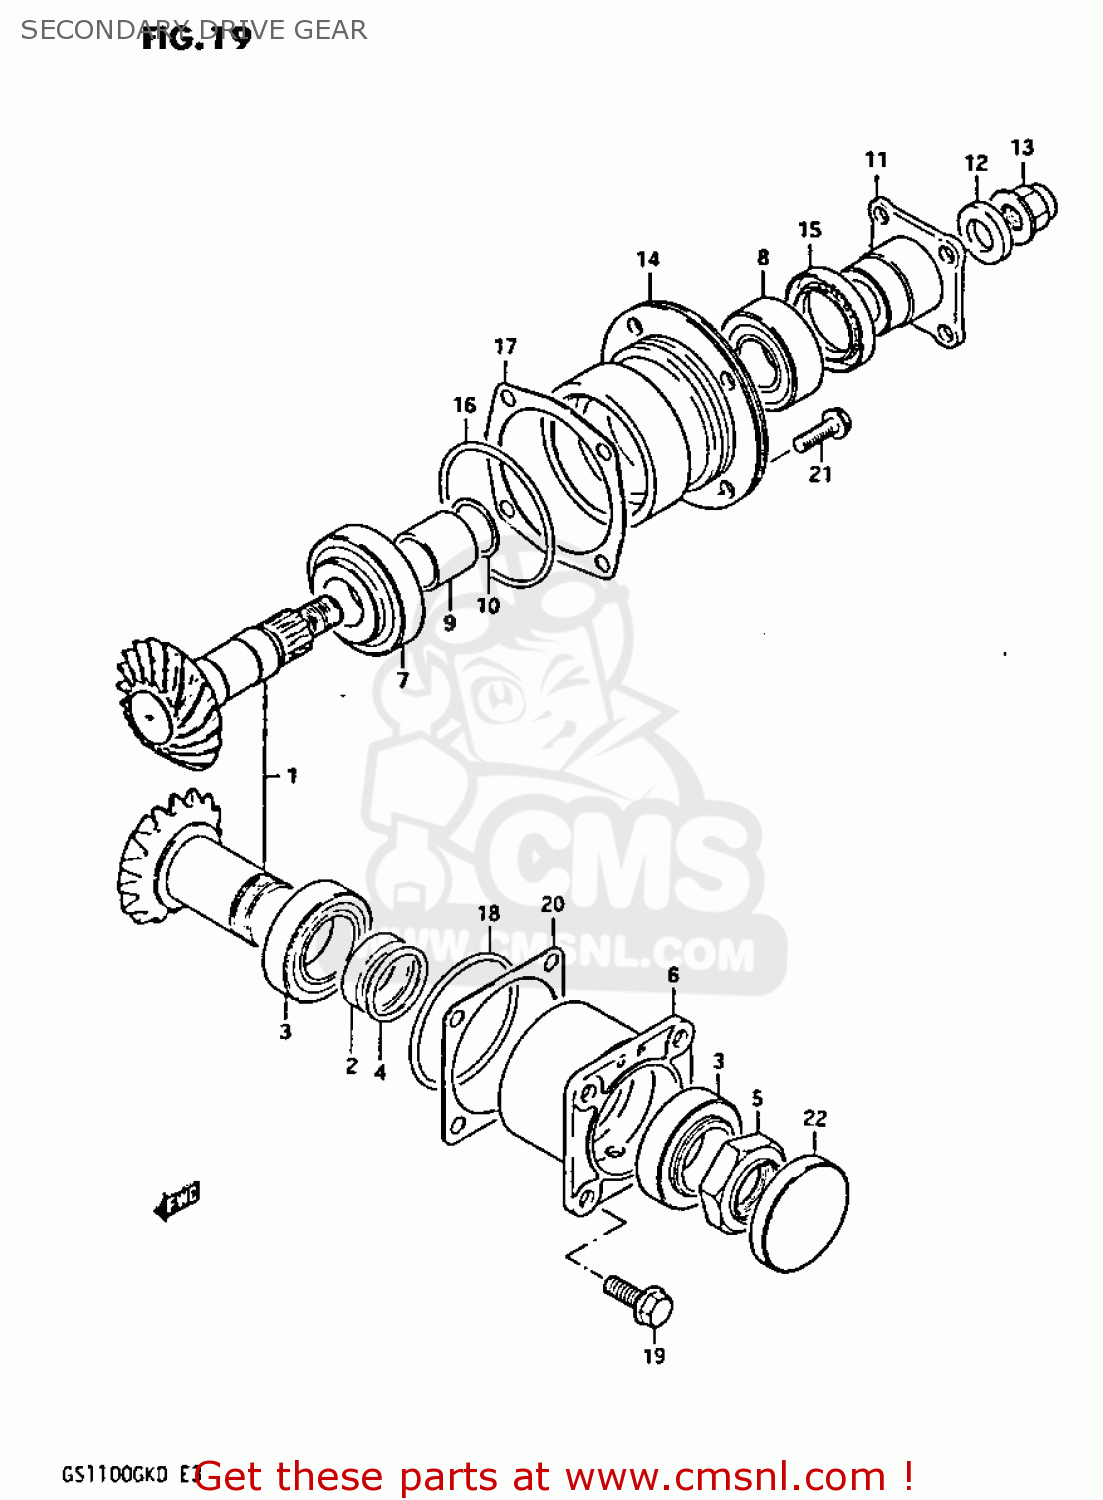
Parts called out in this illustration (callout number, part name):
1	GEAR,SECONDARY DRIVE BEVEL
2	SPACER (32.4X38X12.5)
3	BEARING(32X58X17)
4	SHIM(32X38X2)
5	NUT
6	HOUSING,SECONDARY DRIVE
7	TAPER,ROLLER BEARING
8	BEARING(25X52X16.25)
9	SPACER (25.2X30X40)
10	SHIM (25X30X2
11	FLANGE,UNIVERSAL JOINT
12	WASHER(14X29X4)
13	NUT
14	HOUSING,SECONDARY DRIVE
15	SEAL,OIL(35X52X9)
16	O RING(D:3.1,ID:69.4)
17	SHIM,DRIVEN GEAR HOUSING
18	O RING(D:2.4,ID:62.6)
19	BOLT
20	SHIM,SECONDARY DRIVE
21	BOLT
22	PLUG
